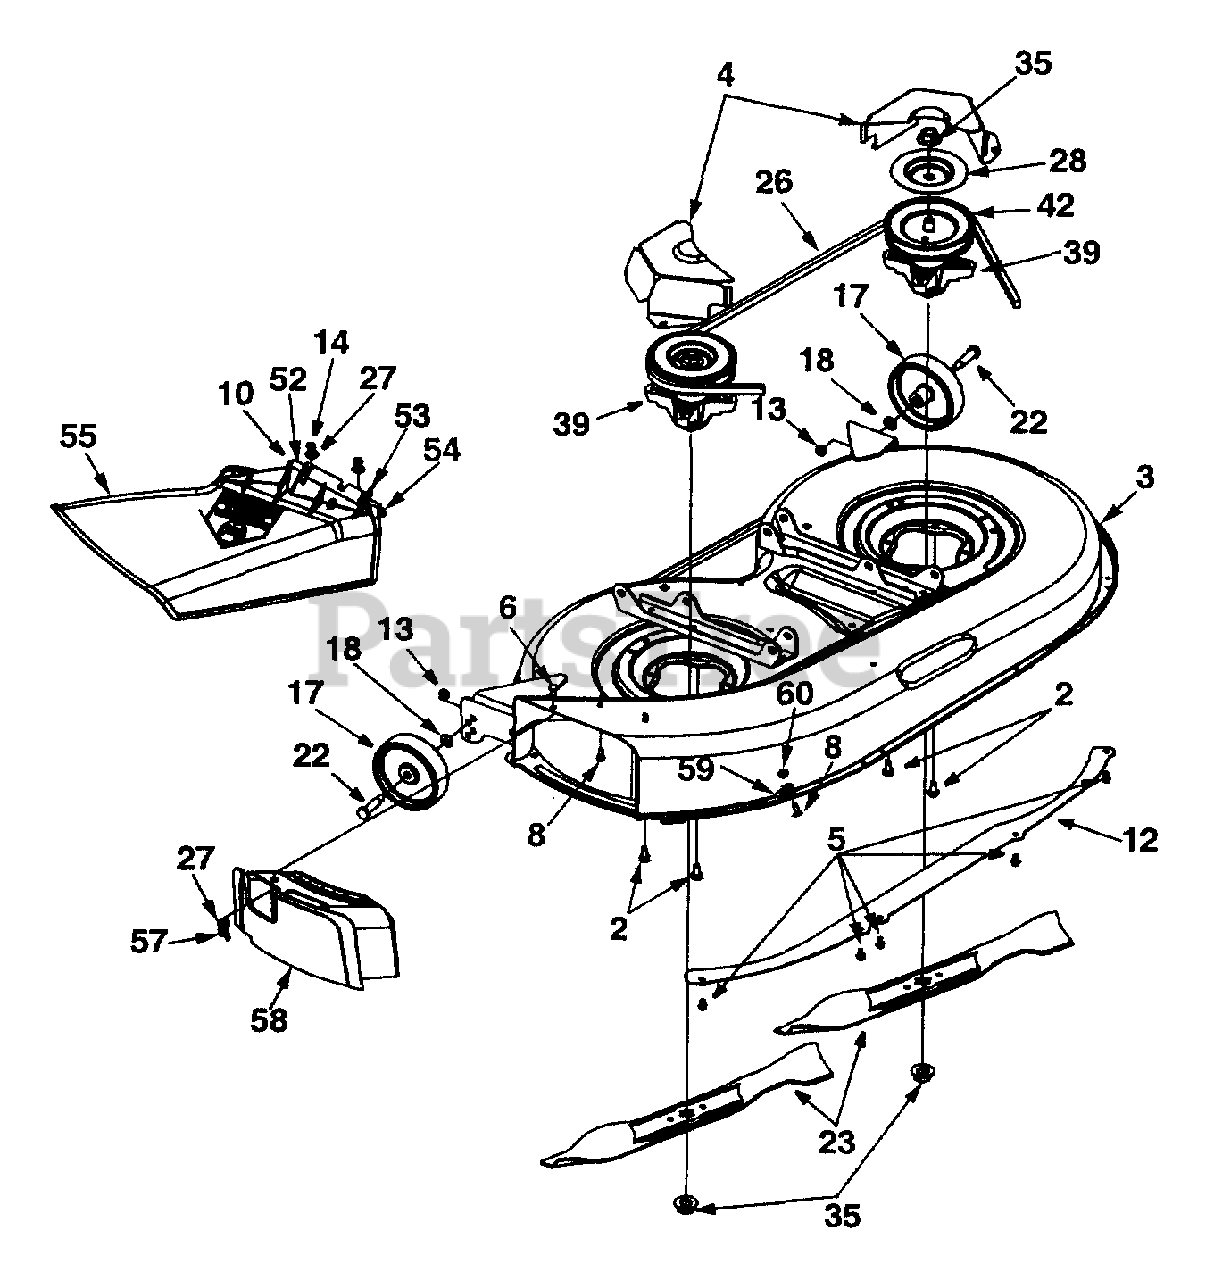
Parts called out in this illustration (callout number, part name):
2	Hex Wash. TT-Tap Scr. 5/16-18 x .75"
5	Hex Wash. Hd. TT-Tap Screw 1/4-20 Thd.
6	Carriage Screw 1/4-20 Thd.
8	Hex Bolt 1/4-20 x .62"
10	Hinge Pin
13	Hex Top L-Nut 3/8-16 Thd.
14	Hex Nut 1/4-20 Thd. (Gr. 5)
17	Deck Wheel-5"
18	Bell-Wash. .40" I.D. x .88" O.D.
22	Shld. Bolt .498" Dia. x 1.53"
23	3 in 1 Blade
26	V-Belt
27	Bell-Wash. 1/4" I.D.
28	Brake Disc
35	Hex Flange Nut 5/8-18 Thd.
39	Blade Spindle Assembly
42	5.75" Dia. Pulley
52	Hinge Mtg. Brkt.
53	Torsion Spring
54	Push Nut
55	Chute Assembly
57	Wing Nut 1/4-20 Thd.
58	Mulching Plug
59	Retainer Hook Brkt.
60	Hex Flange Nut 1/4-20 Thd.
